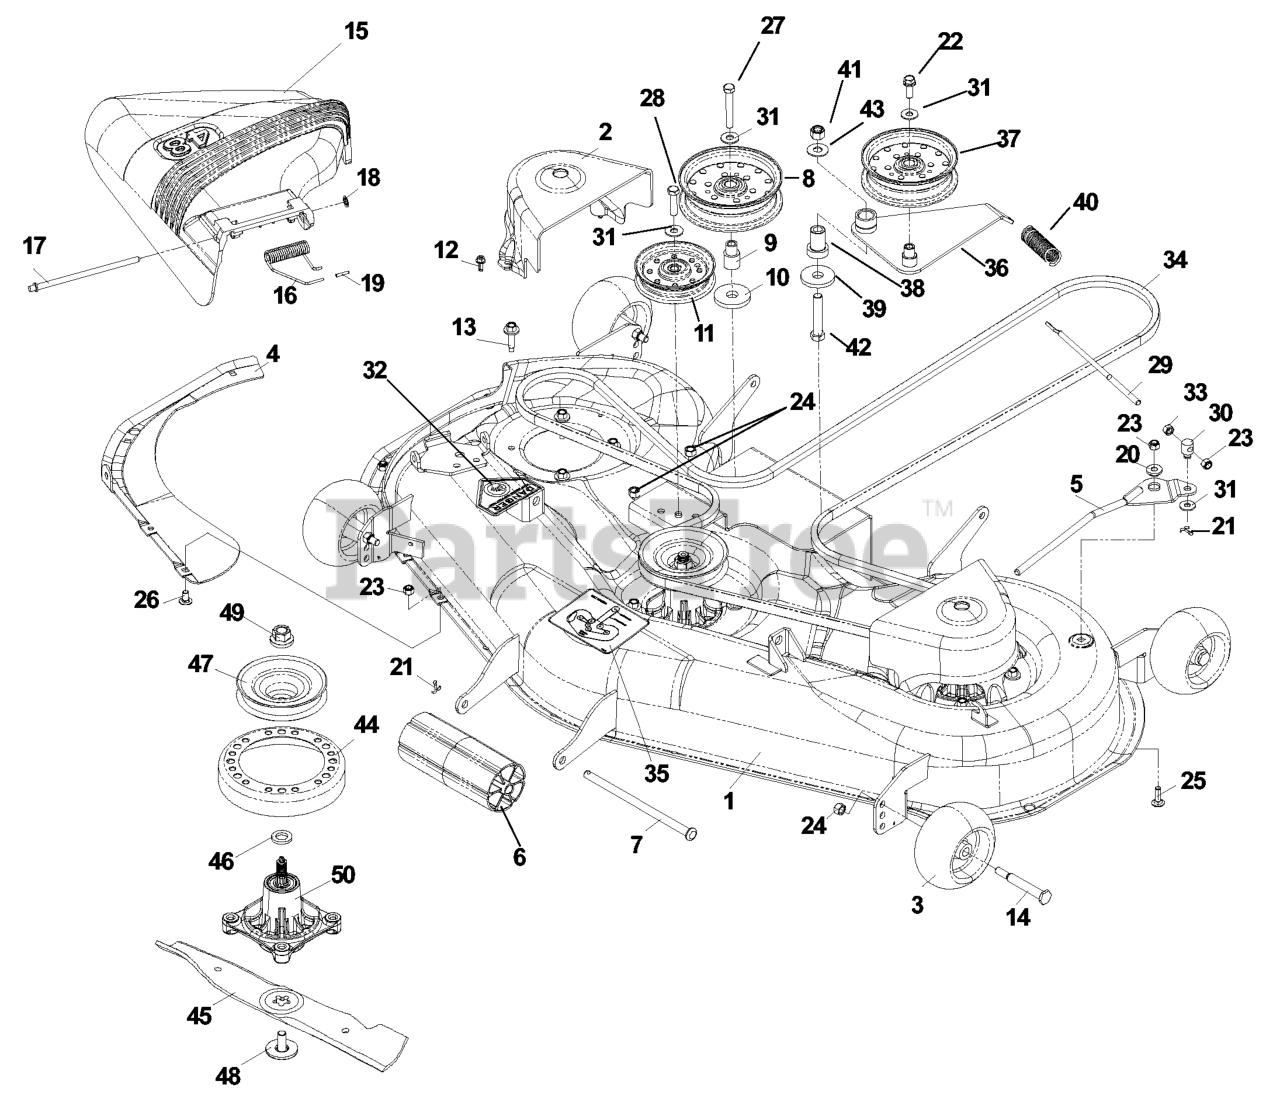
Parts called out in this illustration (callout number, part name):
1	DECK WELDMENT-48"
2	BELT SHIELD
3	GAUGE WHEEL
4	VORTEX MOWER BAFFLE
5	TENSION RELIEF LEVER BLK
6	NOSE ROLLER-48"
7	NOSE ROLLER ROD
8	IDLER PULLEY
9	IDLER BUSHING
10	WASHER, SUPPORT
11	FLAT IDLER PULLEY
12	SCREW- 1/4-20 X 5/8
13	WASHER HEAD SCREW
14	SHOULDER BOLT 1/2X2-5/8 ZD SPE
15	DISCHARGE CHUTE
16	TORSION SPRING
17	HINGE ROD
18	PUSH NUT
19	CAP-SLEEVE
20	PIVOT BUSHING
21	RP_COTTER PIN 1/8 X 3/4
22	4CS 3/8C X 1 SERRATED HEAD
23	NUT 5/16 NYLOC
24	NUT 3/8-16 NYLOC
25	RHSNB 5/16C X 1
26	CARRIAGE BOLT 5/16C X 5/8"
27	SCREW 3/8C X 2 3/4 HEX CAP
28	HCS 3/8-16 X 1 3/4 GR5
29	TENSION RELIEF LINKAGE
31	WASHER 5/16 FLAT
32	DECAL, CPSC
33	NUT 5/16C HEX
34	BELT, DECK
35	DECAL, BELT ROUTING
36	DECK IDLER ARM WELDMENT
37	IDLER PULLEY
38	IDLER SPINDLE
39	SUPPORT PLATE
41	NUT 1/2-13 HEX NYLOC ZD
42	SCREW, 1/2C X 3 HEX CAP
43	WASHER 1/2 FLAT
44	STRIPPER-ROUND-UNIVERSAL
45	BLADE-HIGH LIFT/48"
46	WASHER-SPACER
47	DRIVEN PULLEY-48"
48	BLADE BOLT ASSY-7/16" TB REPL
49	LOCKNUT - 9/16
50	CUTTER HOUSING
